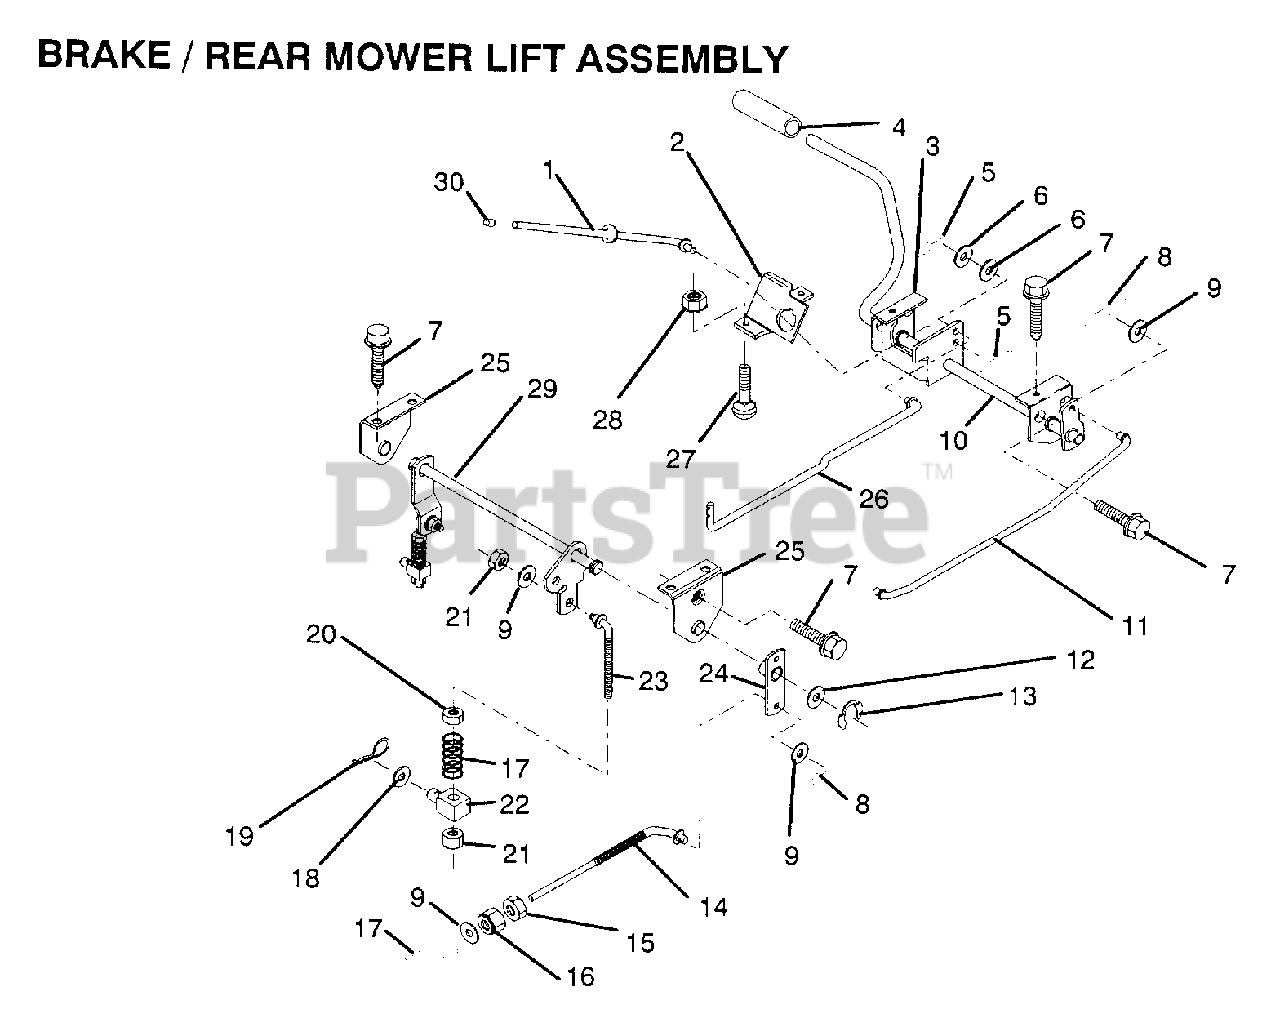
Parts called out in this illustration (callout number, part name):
1	"ROD,PARK BRAKE"
2	"BRKT,PARK BRAKE"
3	"BRKT,CLU PEDAL LH"
4	PEDAL COVER T
6	WASHER
7	SCREW LT
8	COTTER PIN
9	WASHER
11	"ROD,FRT BRAKE"
12	WASHER T
13	KLIP RING
15	NUT
16	NUT
17	SPRING ROD LT
18	WASHER
19	SPRING.RETAINER
20	LOCKNUT
23	"LINK.LIFT.3.5"""
24	BRAKE PIVOT ARM
25	"BRKT,LIFT SHAFT"
26	"ROD,CLUTCH"
29	REAR MOWER LIFT
30	PLUNGER CAP T
